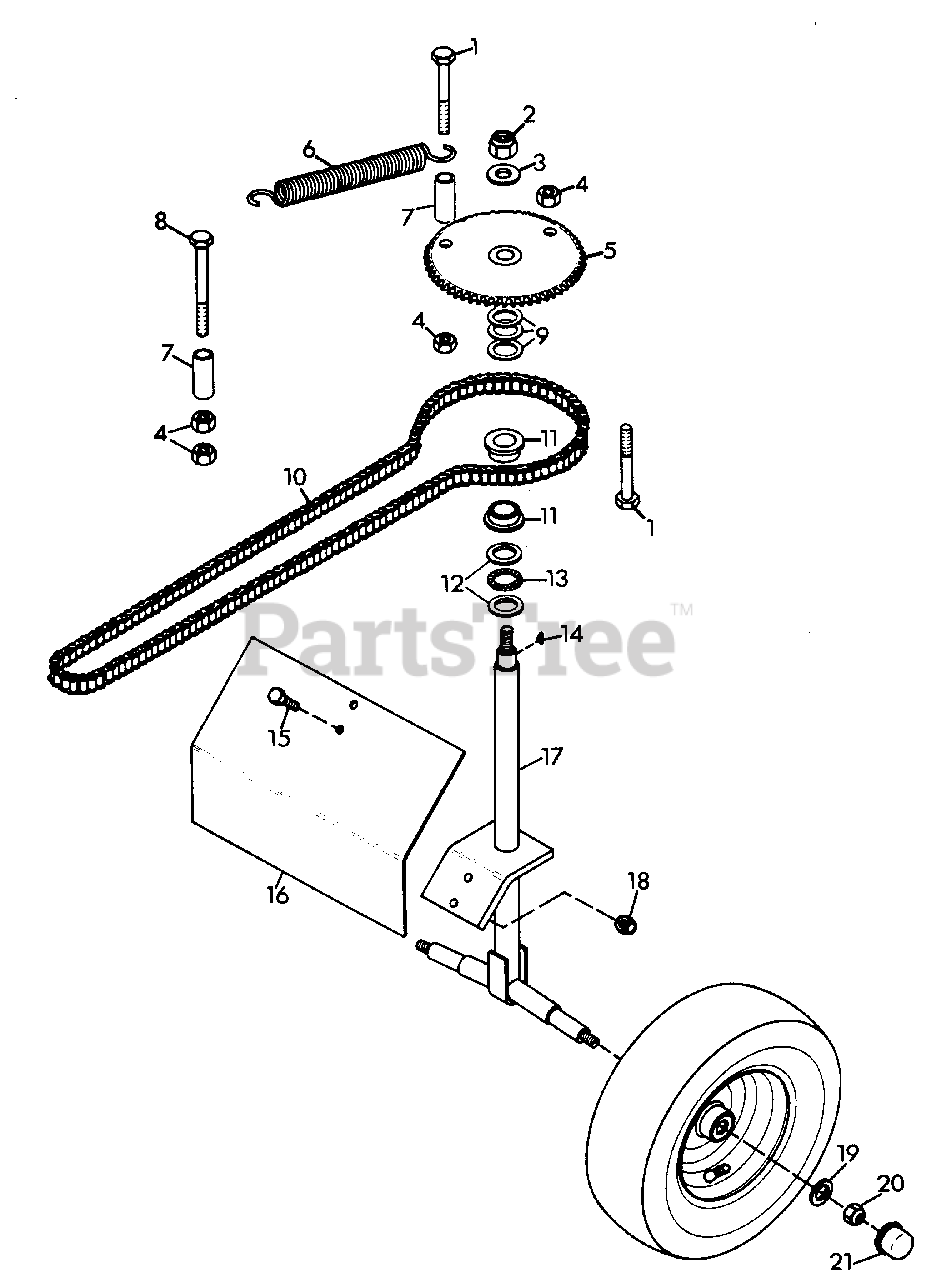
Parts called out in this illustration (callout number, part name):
1	BOLT, HEX 1/2-13X3.25
2	NUT, LOCK 7/8-9
3	WASHER, FLAT .969X2.250X.165
4	NUT, HEX 1/2-13
5	WELDMENT, SPROCKET #40 60T
6	SPRING
7	BUSHING, MOWER PIVOT
8	BOLT, HEX 1/2-13X3.75
9	RACE, THRUST
10	CHAIN, OFC
11	BEARING, FLANGED
12	BEARING, THRUST RACE
13	BEARING, NEEDLE THRUST
14	KEY, WOODRUFF .250X.875 HARD #A
15	BOLT, 1/2-13X1.25
16	FENDER, PRO MASTER
17	WELDMENT, PRO MASTER AXLE
18	NUT, LOCK 1/2-13
19	WASHER, FLAT .812X1.496X.134
20	NUT, LOCK 3/4-10
21	CAP
